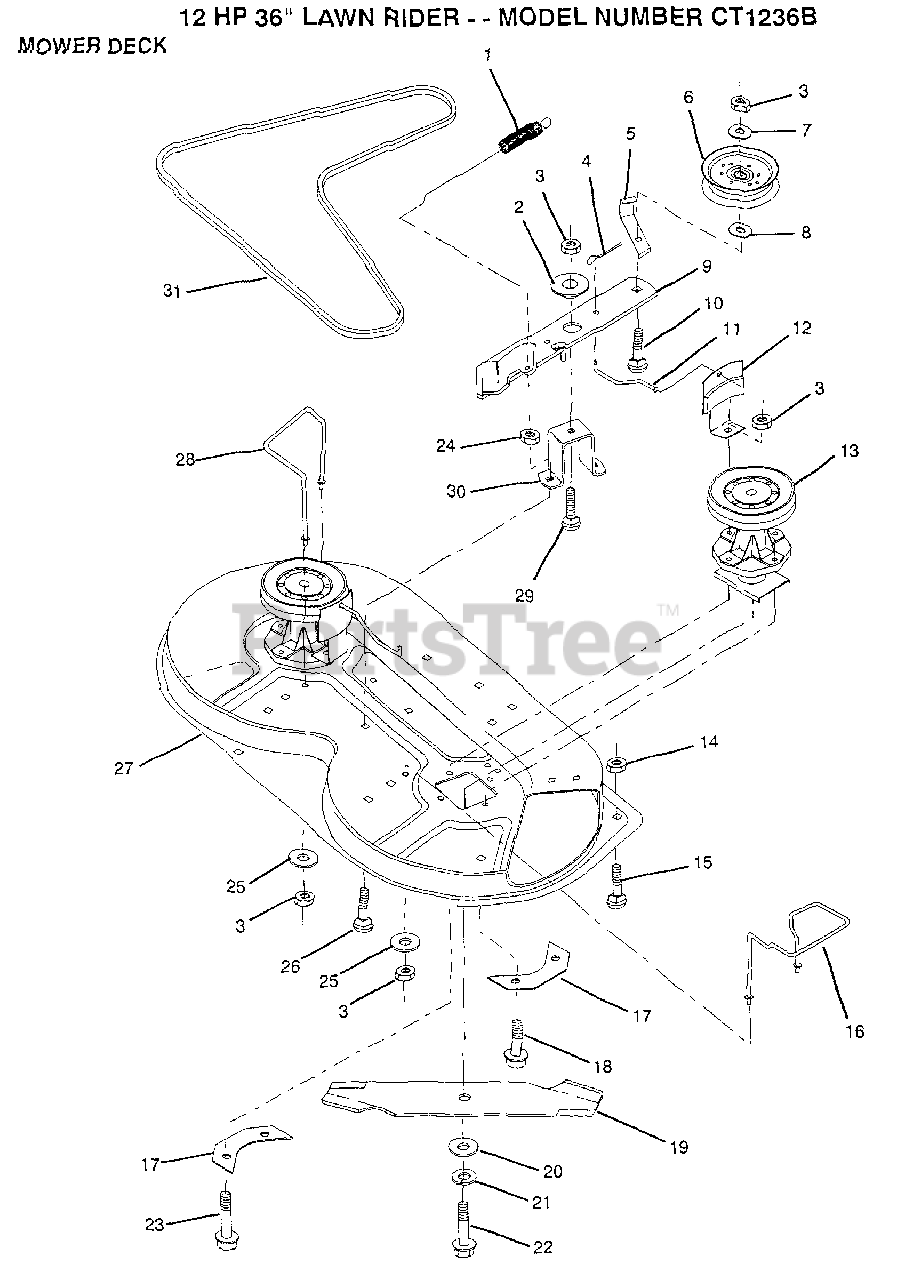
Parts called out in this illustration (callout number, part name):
2	SPACER RETAINER
6	PULLEY IDLER
7	WASHER
8	WASHER GT
10	BOLT CARRIAGE
11	ROD BRAKE
12	BRAKE LT
13	MANDREL ASS'Y
15	BOLT
16	"GUIDE,BELT RH"
17	SUPPORT PLATE LT
18	SCREW
19	"BLADE.36""HIGH LIF"
20	WASHER
22	BOLT.3/8-24X1-1/2
23	SCREW
25	WASHER
26	BOLT
28	GUIDE BELT LH
29	BOLT D
30	"SUPT,IDLER ARM"
31	BELT.MOWER.79.75
